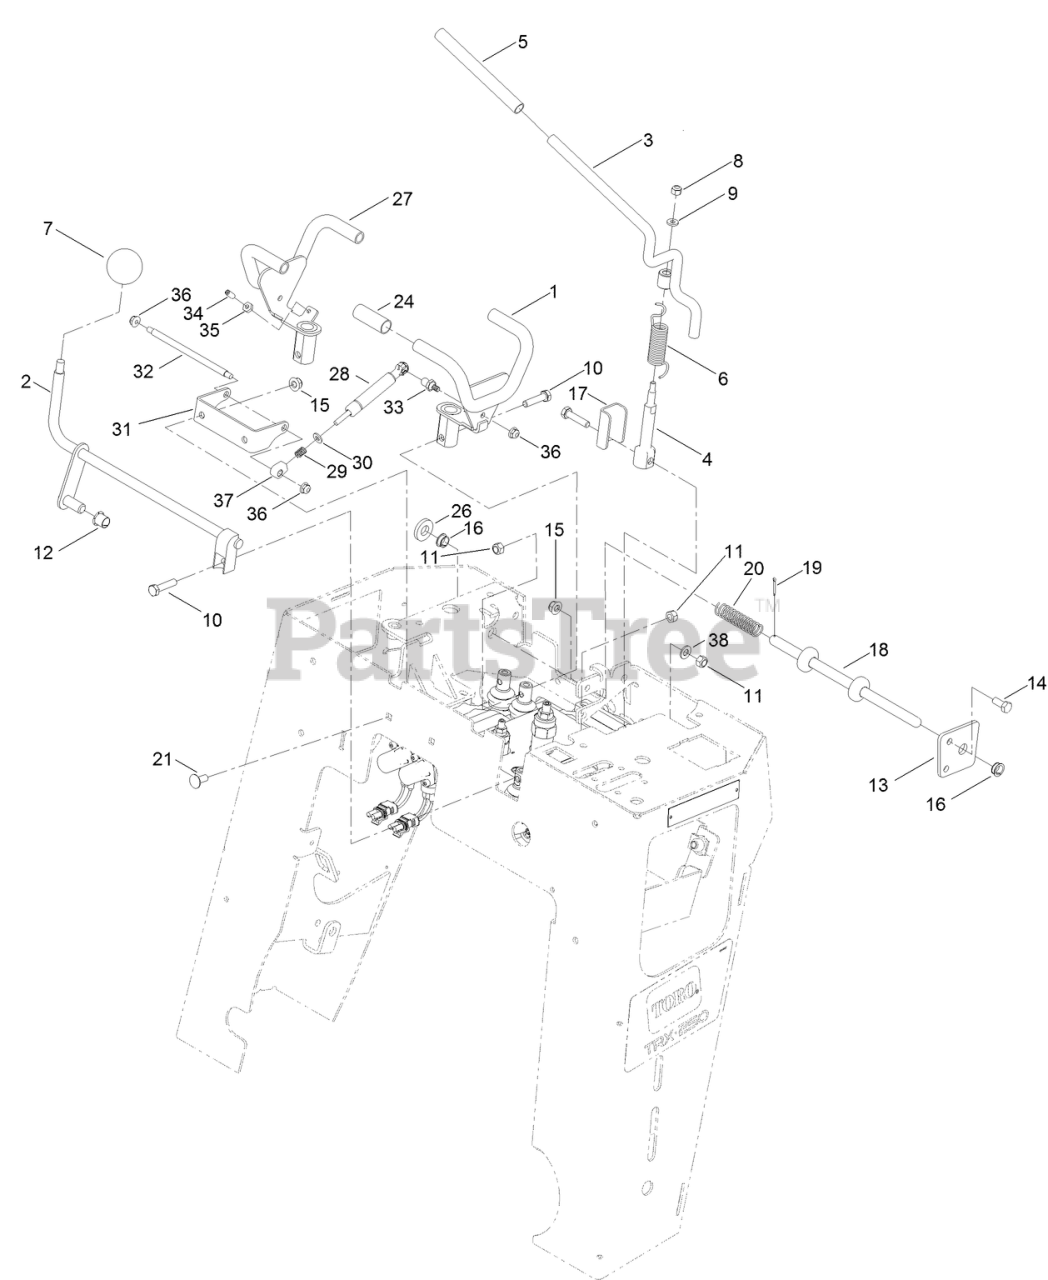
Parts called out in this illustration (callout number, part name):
1	HANDLE-TRACTION, LH
2	LEVER-LIFT
3	AUXILIARY LEVER ASM
4	LEVER-DRIVE, CHAIN
6	SPRING-TORSION
8	NUT-LOCK, NI
9	WASHER-FLAT
10	SCREW-HH
11	NUT-LOCK, NI
12	BUSHING-NYLINER
13	PLATE-BUSHING
14	SCREW-HH
15	NUT-HF, NI
16	BUSHING
17	BRACKET-LEVER
18	ROD-LOCKOUT
19	PIN-COTTER
20	SPRING-COMPRESSION
21	SCREW-CARR
26	WASHER-HARDENED
27	HANDLE-TRACTION, RH
28	DAMPER
29	SPRING-COMPRESSION
30	WASHER-SPCL
31	BRACKET-DAMPER
32	ROD-DAMPER
33	STUD-BALL
34	SCREW-SET, HS
35	NUT-JAM
36	NUT-HF
37	FITTING-CLEVIS
38	WASHER-PLAIN
